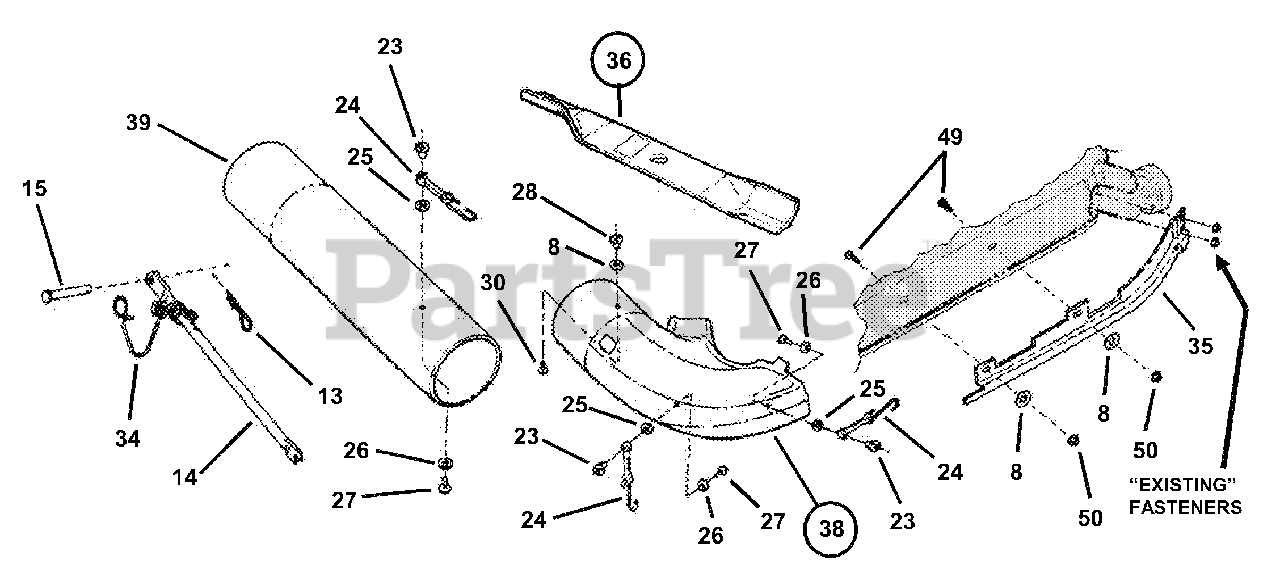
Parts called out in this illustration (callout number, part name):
8	WASHER, 3/8" Flat
13	PIN, 3/32 x 1-1/2" Hair
14	BRACE, Rear
15	PIN, 5/16 x 1-11/16" Clevis
23	NUT, #10-24 x 5/8" Weld
24	STRAP, Adapter/Tube
25	WASHER, 3/16" Flat
26	WASHER, 7/32" Flat
27	SCREW, #10-24 x 5/8" Pan Hd.
28	TEENUT, 5/16-18
30	SCREW, 5/16-18 x 5/8" Mach.
34	ASS'Y, Spring & Hook
35	BAFFLE, 38" Deck
36	ASS'Y High Lift Blade & Decal (Decal No. 44686)
38	ADAPTER,
39	TUBE, Grass (37" long)
49	SCREW, 5/16-18 x 3/4" Cap
50	NUT, 5/16-18 Hex Ctr. Lock
